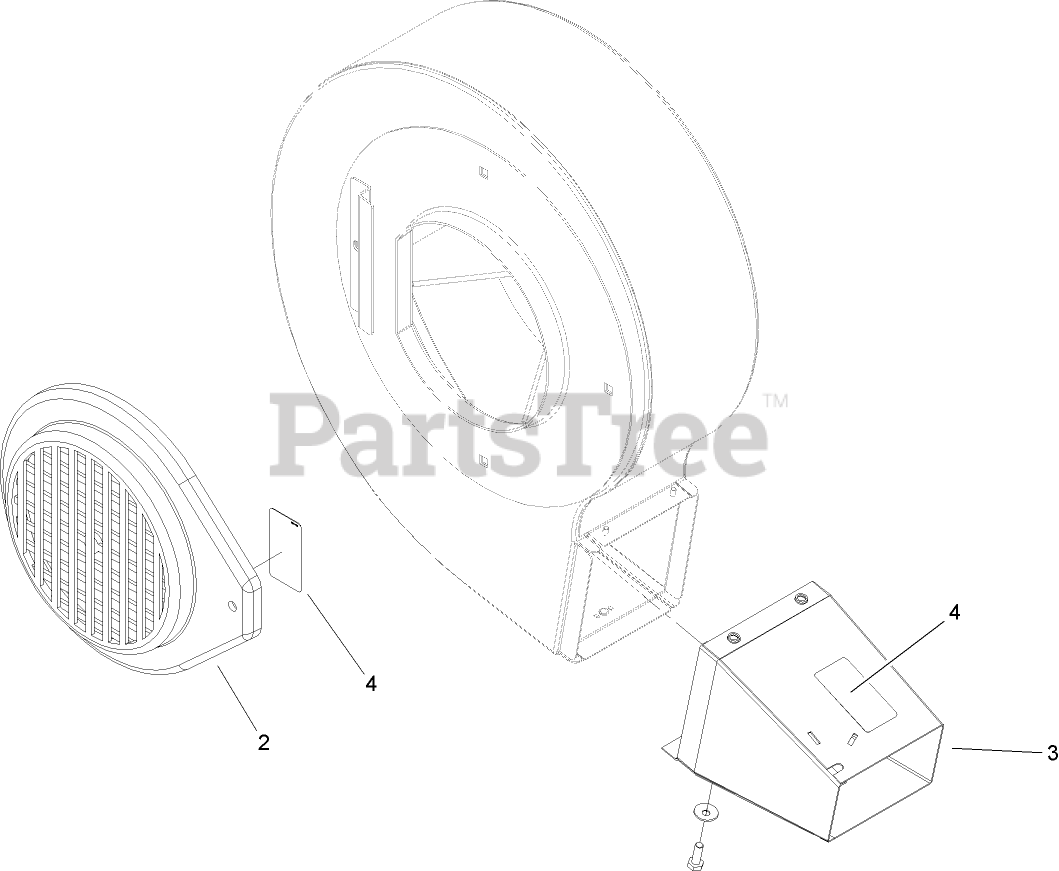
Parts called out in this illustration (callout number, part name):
2	INTAKE-BLOWER
3	EXHAUST-BLOWER
4	DECAL-CAUTION, BAG
